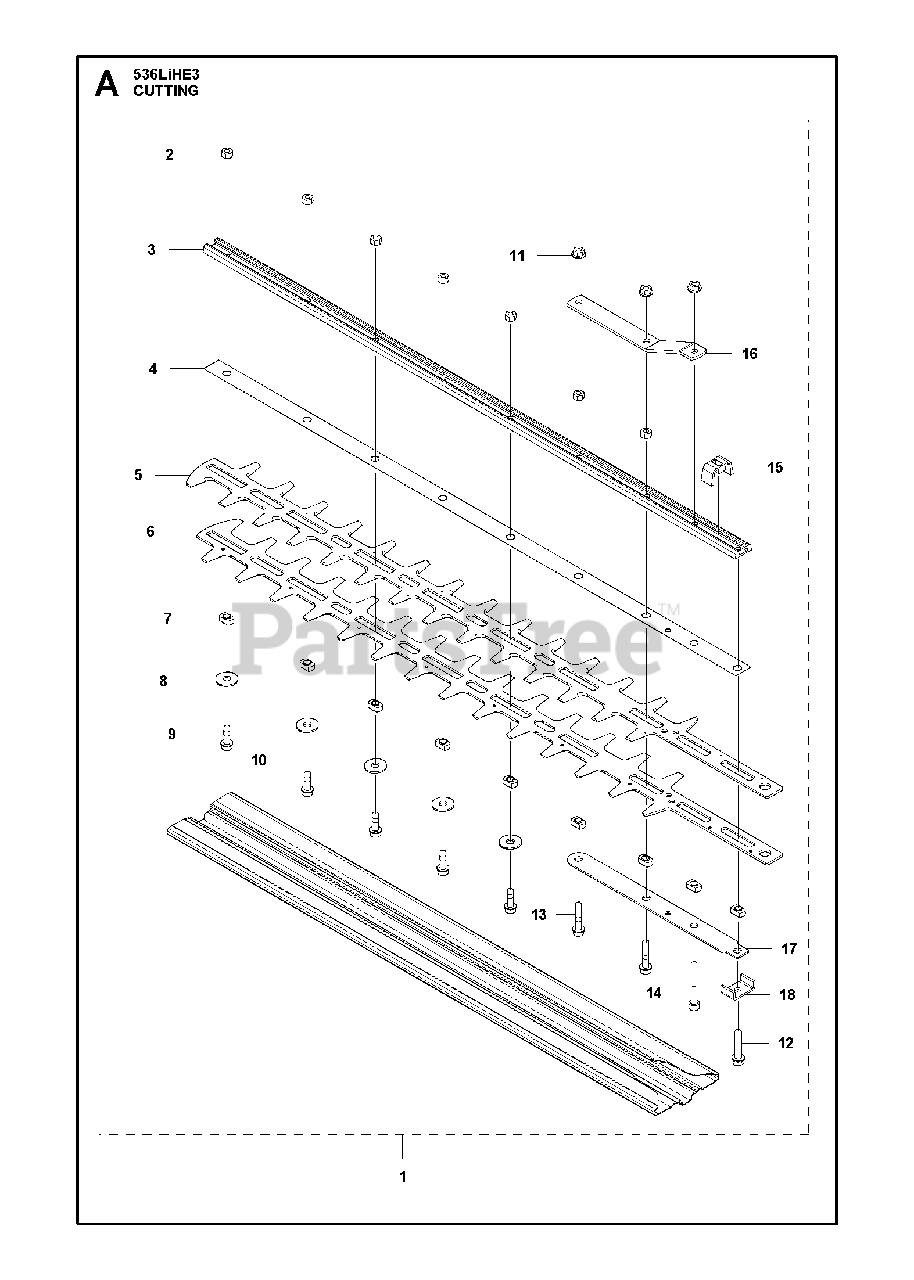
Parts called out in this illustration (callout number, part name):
1	CUTTING DECK ASSY 55
2	HEXAGON NUT ISO 4032-M5-10
3	BAR CUTTING DECK 55
4	WEAR PLATE CUTTING DECK 55
5	Blade Assembly, 55
6	Blade Assembly, 55
7	Cutting Deck Spacer
8	WASHER 6,4X18X1,5
9	SCREW IHSCFM M5X16 10.9 ZN/FE
10	TRANSPORT GUARD CUTTING DECK 5
11	HEXAGON NUT FLANGE M5 8 ZN/FE
12	SCREW
13	SCREW IHSCFM M5X25 10.9 ZN/FE
14	SCREW
15	GASKET
16	SUPPORT CUTTING DECK
17	BAR LOWER
18	BRACKET CUTTING DECK
